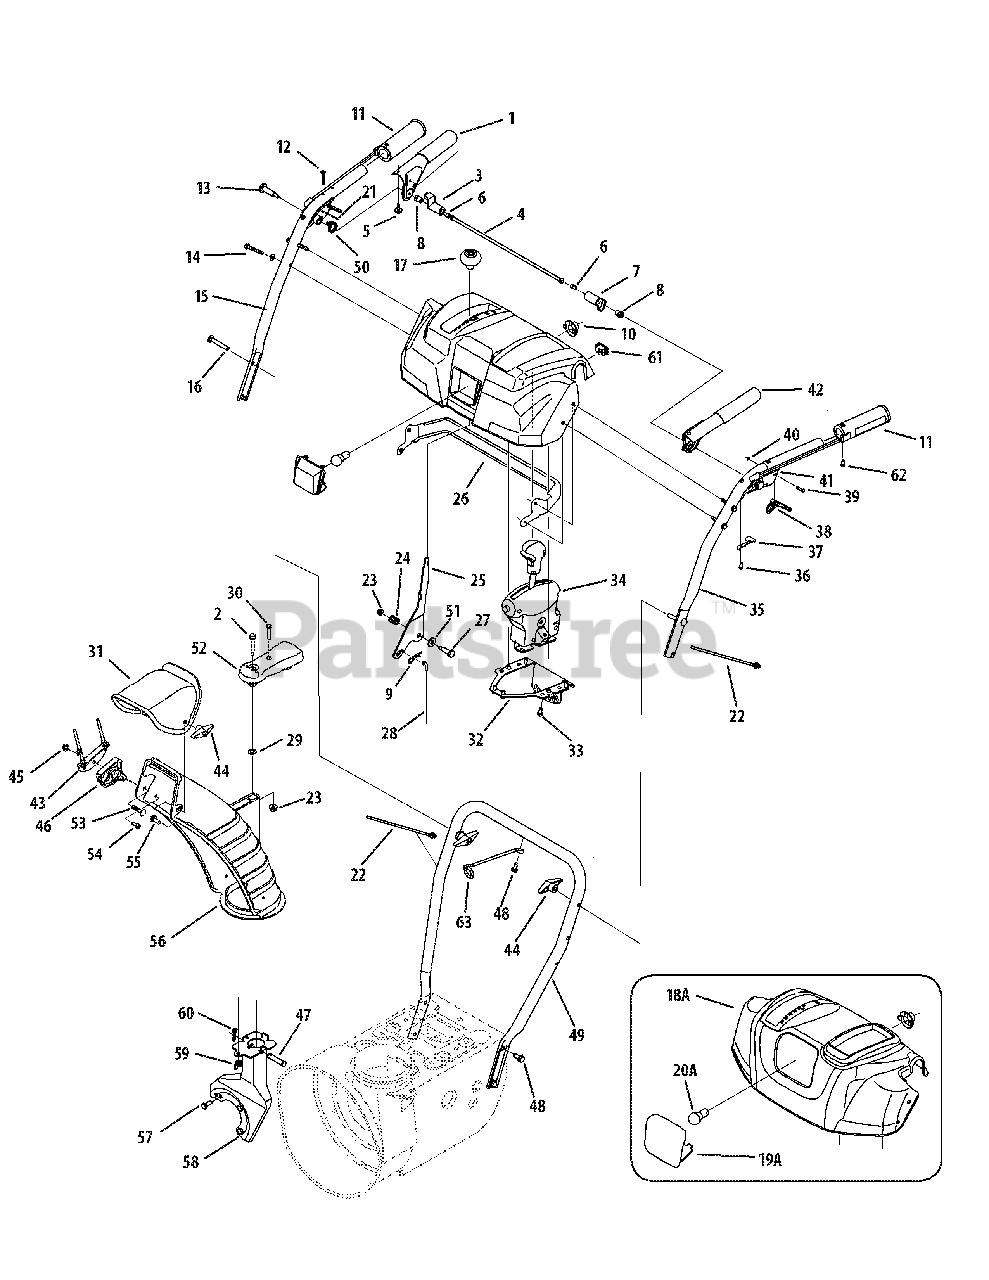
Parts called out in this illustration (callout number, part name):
1	Handle Engagement Assembly RH
2	Flange Shoulder Screw
3	Lock Plate
4	Pivot Rod
5	Rubber Bumper
6	Socket Screw, 1/4-20 x .5
7	Clutch Lock Cam
8	Shoulder Nut, 1/4-20
9	Click Pin
10	Light Socket
11	Heated Handle Grip
12	Screw, #10-24 x 0.375
13	Shoulder Screw, 1/4-20 x .437 x 1.345
14	Screw, 1/4-20 x 1.625
16	Carriage Screw, 5/16-18 x 2.25
17	Shift Knob
18A	L-Style Handle Panel
19A	L-Style Lens
21	Handle Clutch Lock - RH
22	Cable Tie
23	Flange Lock Nut, 1/4-20
24	Compression Spring
27	Shoulder Screw
28	Speed Selector Cable
29	Flat Washer, .25 x .630 x .0515
30	Screw, #10-16 x .500
31	Upper Chute
33	Hi-Lo Screw, 1/4-15 x 0.5
34	4-Way Tall Chute Control™ Assembly
36	Screw, #8-16 x 0.50
37	Clutch Lock Spring
38	Steering Control
39	Pin, 3/16
40	E Ring
41	Handle Clutch Lock - LH
42	Handle Engagement Assembly LH
44	Wing Knob
45	Flange Lock Nut, 5/16-18
46	Chute Tilt Cable Guide
47	Clevis Pin
48	Hex Screw
50	Torsion Spring
51	Flat Washer
52	Joystick Pulley Cover
53	Carriage Bolt, 5/16-18 x 1.50
54	Hi-Lo Screw, 1/4-15 x .75
55	Carriage Bolt, 5/16-18 x 1.0
56	Lower Chute
57	Hex Screw, 5/16-24 x .750
58	Chute Support Bracket
59	Wing Nut, 1/4-20
60	Bow Tie Cotter Pin
61	Heated Grip Switch
62	AB Screw
63	Cable Guide
